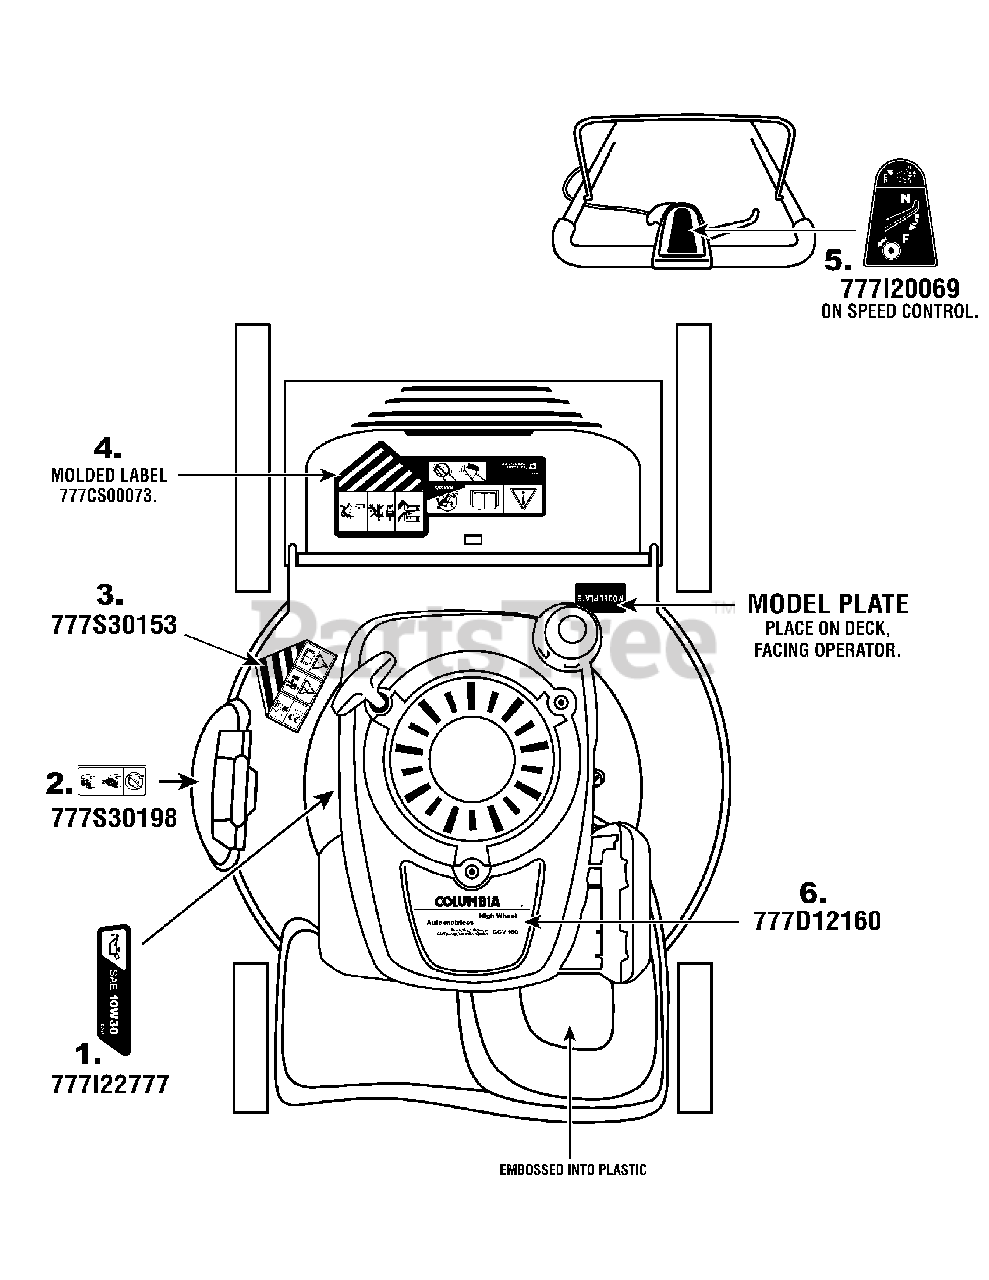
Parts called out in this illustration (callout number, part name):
3	LABEL-DANGER CHUTE
4	LABEL:MOWER:DISCHRG DOOR SAFETY
5	LBL.EXP.PICT.SELF PROP MECH
6	LABEL-ENG SHROUD
